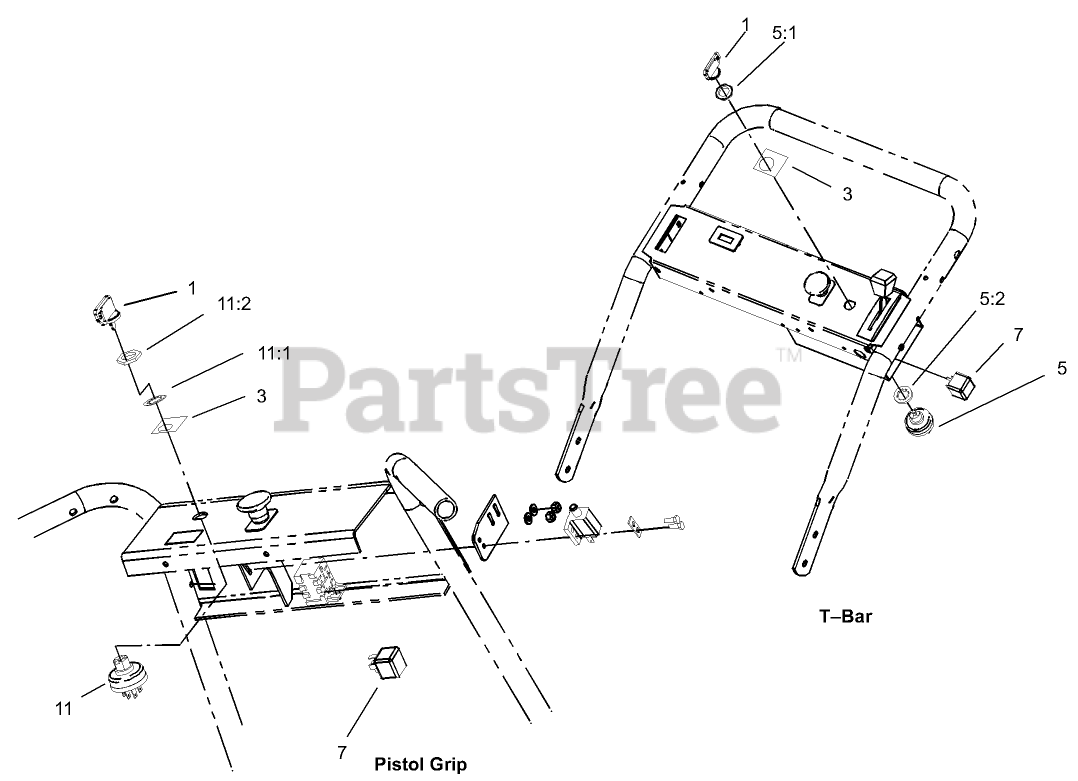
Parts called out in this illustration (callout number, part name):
1	KEY-IGNITION
3	Decal-Electric Start
5	KEY SWITCH ASM
5:2	WASHER-LOCK
7	RELAY
11	Key Switch ASM
11:1	WASHER-TOOTH, INTERNAL
11:2	NUT-HH
